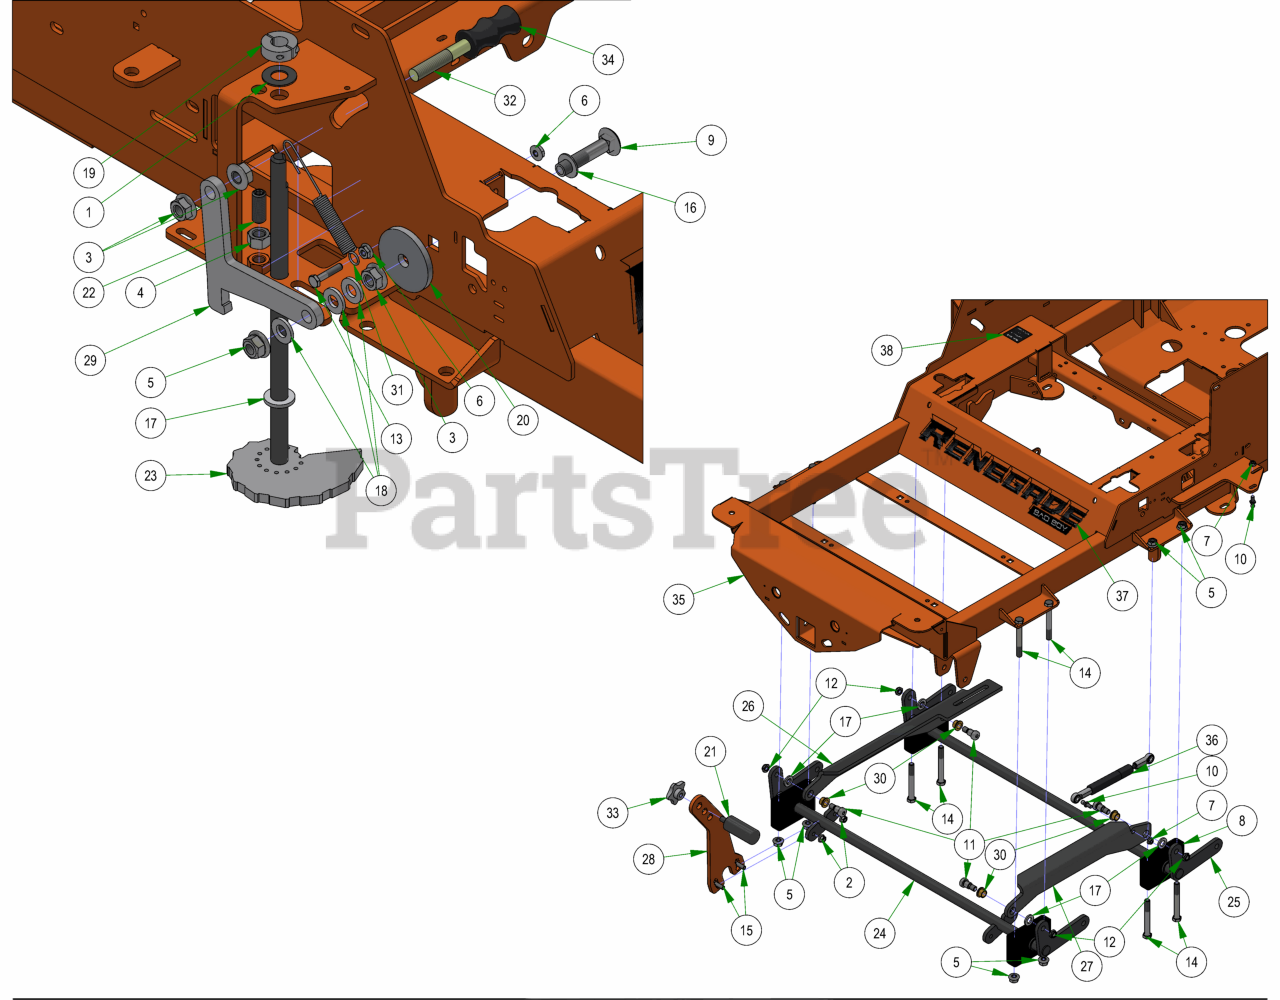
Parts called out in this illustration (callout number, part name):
1	.625 ID x 1.250 OD x .062 THK F/W Nylon
2	3/8-16 NYLON INSERT FLANGE LOCKNUT (GR.F) ZINC
3	1/2-13 HEX SERRATED FLANGE NUT HARD/ZINC
4	1/2-13 HEX NUT ZINC
5	1/2-13 NYLON INSERT FLANGE LOCKNUT ZINC
6	1/4-20 HEX SERRATED FLANGE NUT HARD/ZINC
7	5/16-18 HEX SERRATED FLANGE NUT HARD/ZINC
8	Pillow Block Assembly
9	2 1/2 x 1/2 Carriage Bolt
10	10mm Damper Ball Stud-XP Linkage
11	5/8 X 5/8 SOCKET SHOULDER BOLT ZINC YELLOW
12	1/2-13 NYLON INSERT JAM LOCKNUT ZINC
13	1/4-20 X 1-1/4 HEX CAP SCREW (GR.5) ZINC
14	1/2-13 X 4 HEX CAP SCREW (GR.8) ZINC YELLOW
15	3/8-16 X 1-1/4 CARRIAGE BOLT ZINC
16	.517 SQ WDTH ID X .937 OD X .060 THICK F/W PHOS/OIL
17	.635 ID X 1.120 OD X .140 THICK FLAT WASHER NYLON
18	.505 ID X 1.000 OD X .125 THICK FLAT WASHER NYLON
19	5/8" Split Collar
20	MZ Deck Idler Spacer
21	Knurled Pedal
22	Dial Rod Plunger
23	2019 Outlaw Gen2 Deck Height Dial Rod Assy
24	2019 Outlaw Actuator - Front
25	2019 Outlaw Actuator - Rear
26	2019 Actuator Linkage – Right – Black
27	2019 Actuator Linkage - Left - Black
28	Foot Lift Upright Lever
29	2019 Outlaw Deck Travel Lock
30	.627 ID X .753 OD X .500 LGTH X 1.000 FLG OD X .094 FLG THICK FLANGED BEARING OIL-IMPREG BRNZ
31	Brake Spring
32	Seat Bracket Pin
33	Foot Pedal Knob 1/2-13
34	Travel Lock Rubber Grip
35	2022 Horizontal Diesel Frame
36	250lb Gas Spring - 61" Deck
37	Renegade Front Cover Decal
38	2019 Deck Release Decal
